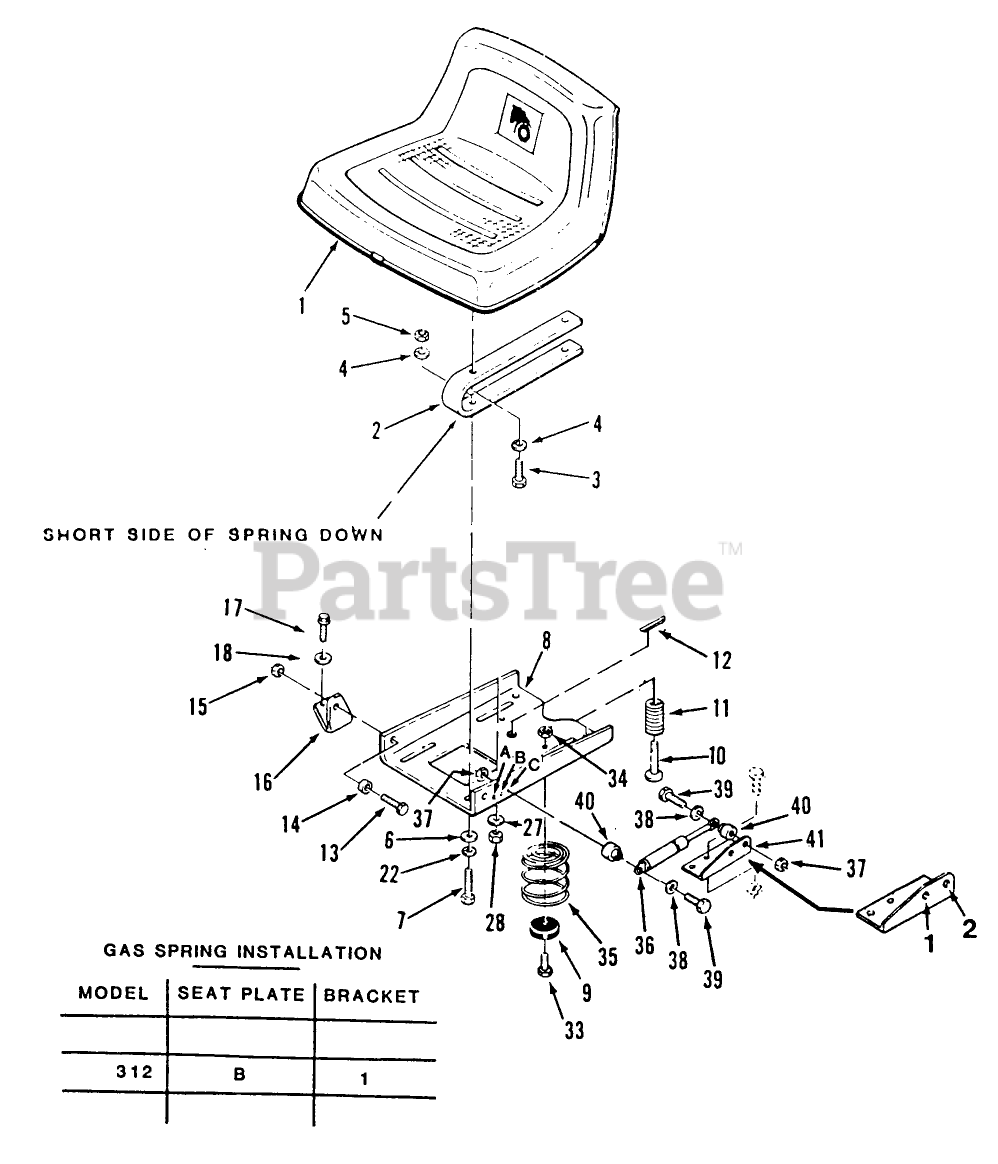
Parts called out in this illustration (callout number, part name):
6	WASHER 5/16 SAE
9	BUMPER
11	SPRING-SEAT SWITCH
14	BUSHING
16	BRACKET-PIVOT R.H *B (NS)
18	WASHER 5/16 SAE
36	GAS SPRING
40	SPACER
41	BRACKET-CYLINDER *R
